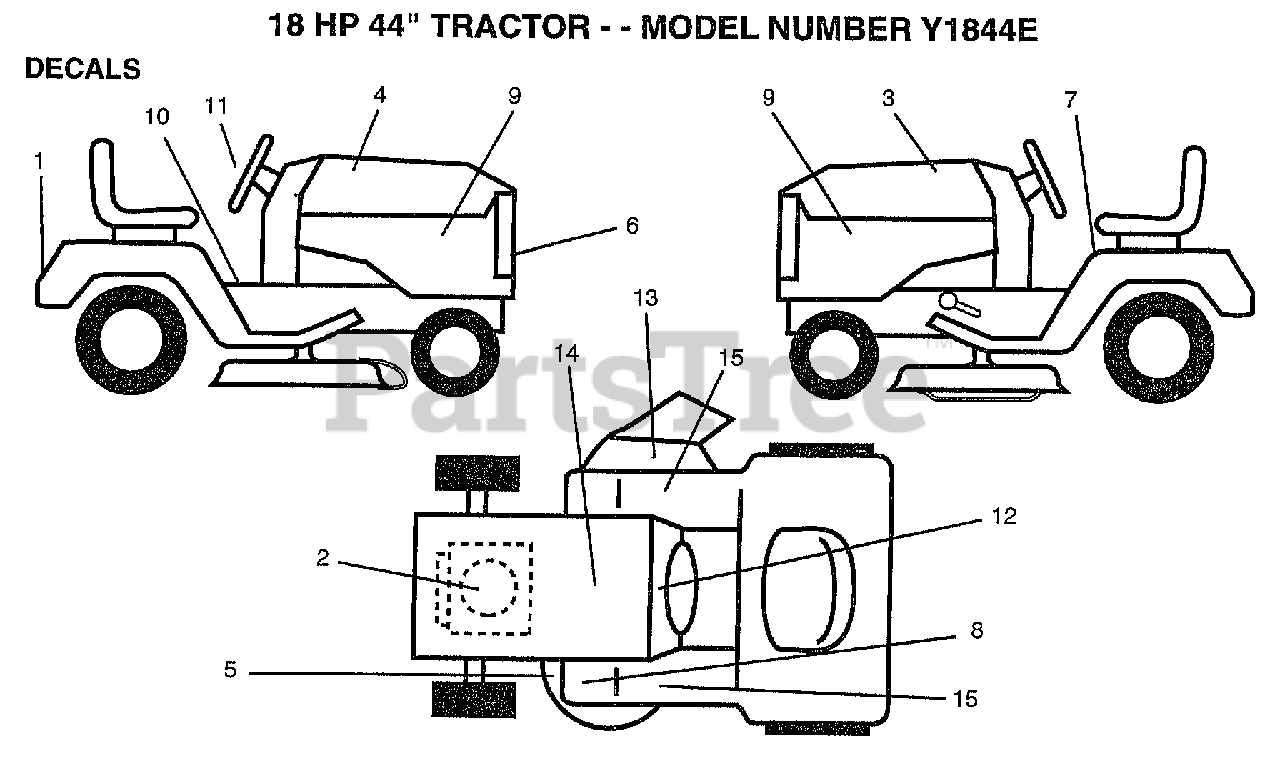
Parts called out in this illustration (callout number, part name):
2	"DECAL,HP ENGINE"
3	DECAL HOOD LH
5	"DECAL.V.BELT.44"""
6	DECAL.GRILL.YARDP
7	DECAL CAUTION
8	DECAL T
9	DECAL.PANEL.SIDE
10	DECAL BRAK PARK
11	DECAL.INS.WHL.STG
12	DECAL.DASH.INSTR.
13	"DECAL, WARNING"
14	DECAL
15	FOOTREST PAD
